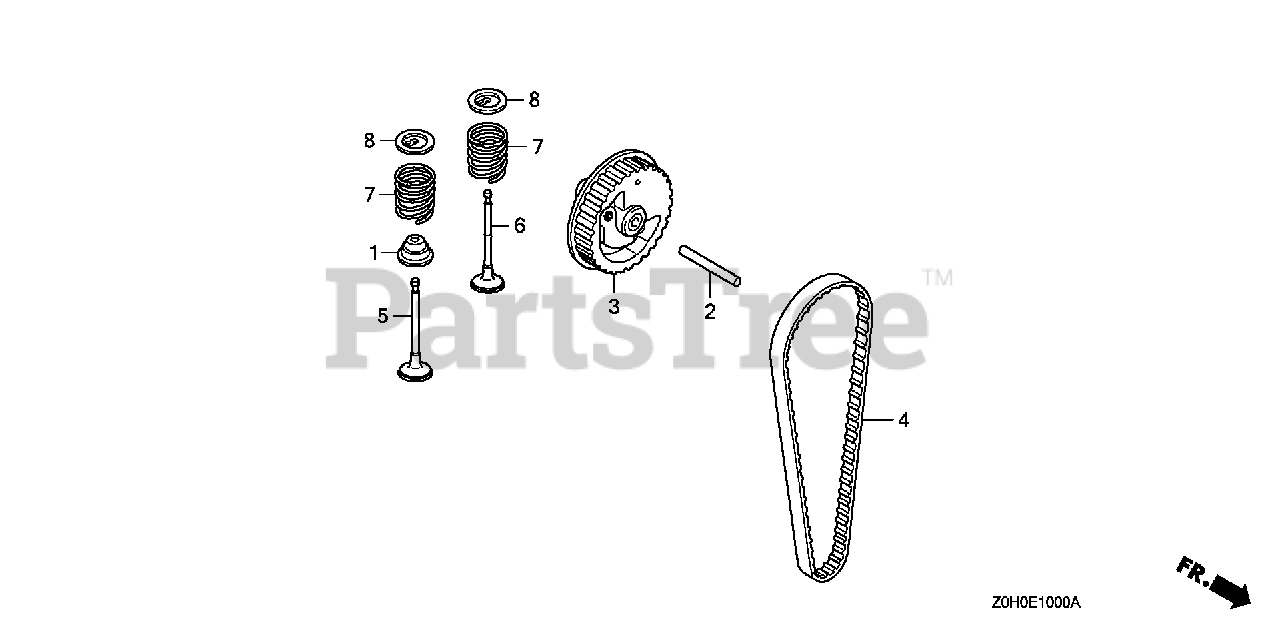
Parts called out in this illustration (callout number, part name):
1	SEAL, VALVE STEM
2	ROLLER (4X29.8)
3	PULLEY, CAMSHAFT
4	BELT, TIMING (71ZU5 G-310)
5	VALVE, IN.
6	VALVE, EX. (HE)
6	VALVE, EX. (EE)
7	SPRING, VALVE
8	RETAINER, VALVE SPRING
